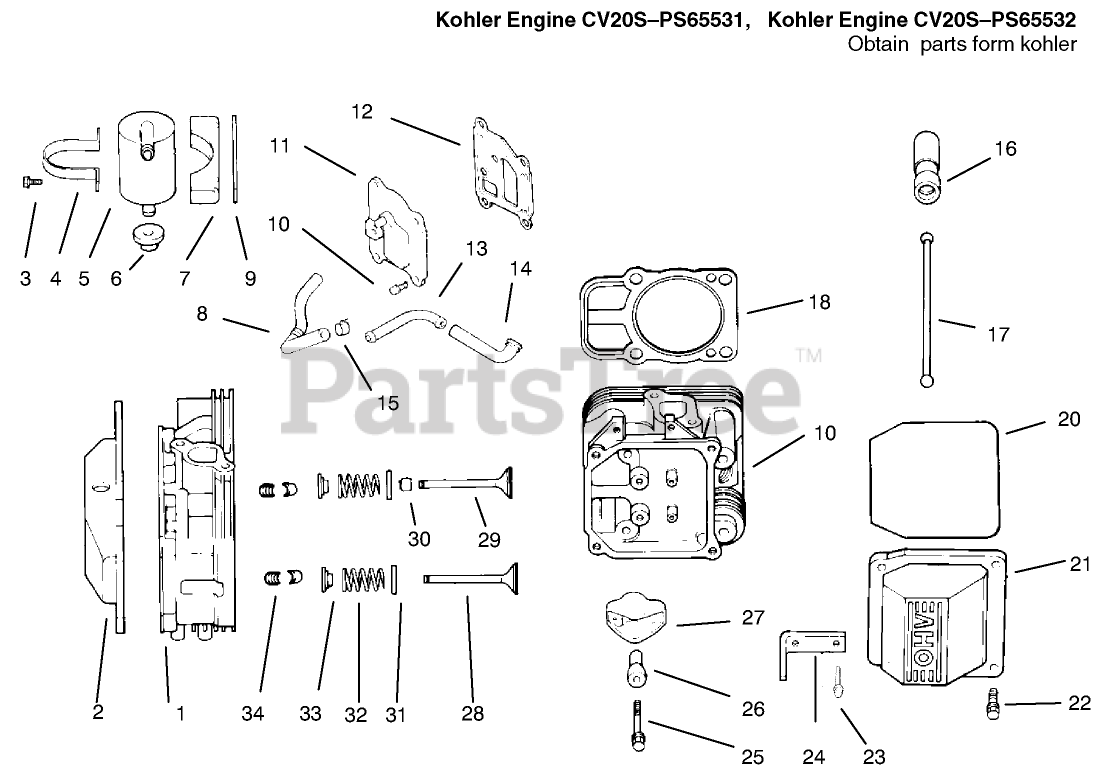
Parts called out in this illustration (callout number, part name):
1	Head ASM-#1 Cylinder (Only On: 72103, 72083)
2	Cover-Rocker (Only On: 72103)
3	Kit-Breather INCL 4 (Only On: 72103)
4	Grommet-Rubber (Only On: 72103)
5	Cover-Breather (Only On: 72103)
7	Hose-Breather (Only On: 72103)
8	Kit-Retainer
9	Cap-Valve Spring
10	Spring-Valve
11	Retainer-Spring
12	Valve-Exhaust
13	Valve-Intake
14	Seal-Valve Stem
15	Fitting (Only On: 72103)
16	Hose-Breather (Only On: 72103)
17	Lifter-Valve
18	Rod-Push (Only On: 72103,72083)
19	Gasket-Cylinder Head
20	Head ASM-#2 Cylinder (Only On: 72103, 72083)
21	Arm-Rocker (Only On: 72103,72083)
22	Ball-Rocker Pivot
24	Cover-Rocker (Only On: 72103)
25	Screw
27	Strap-Lifting
